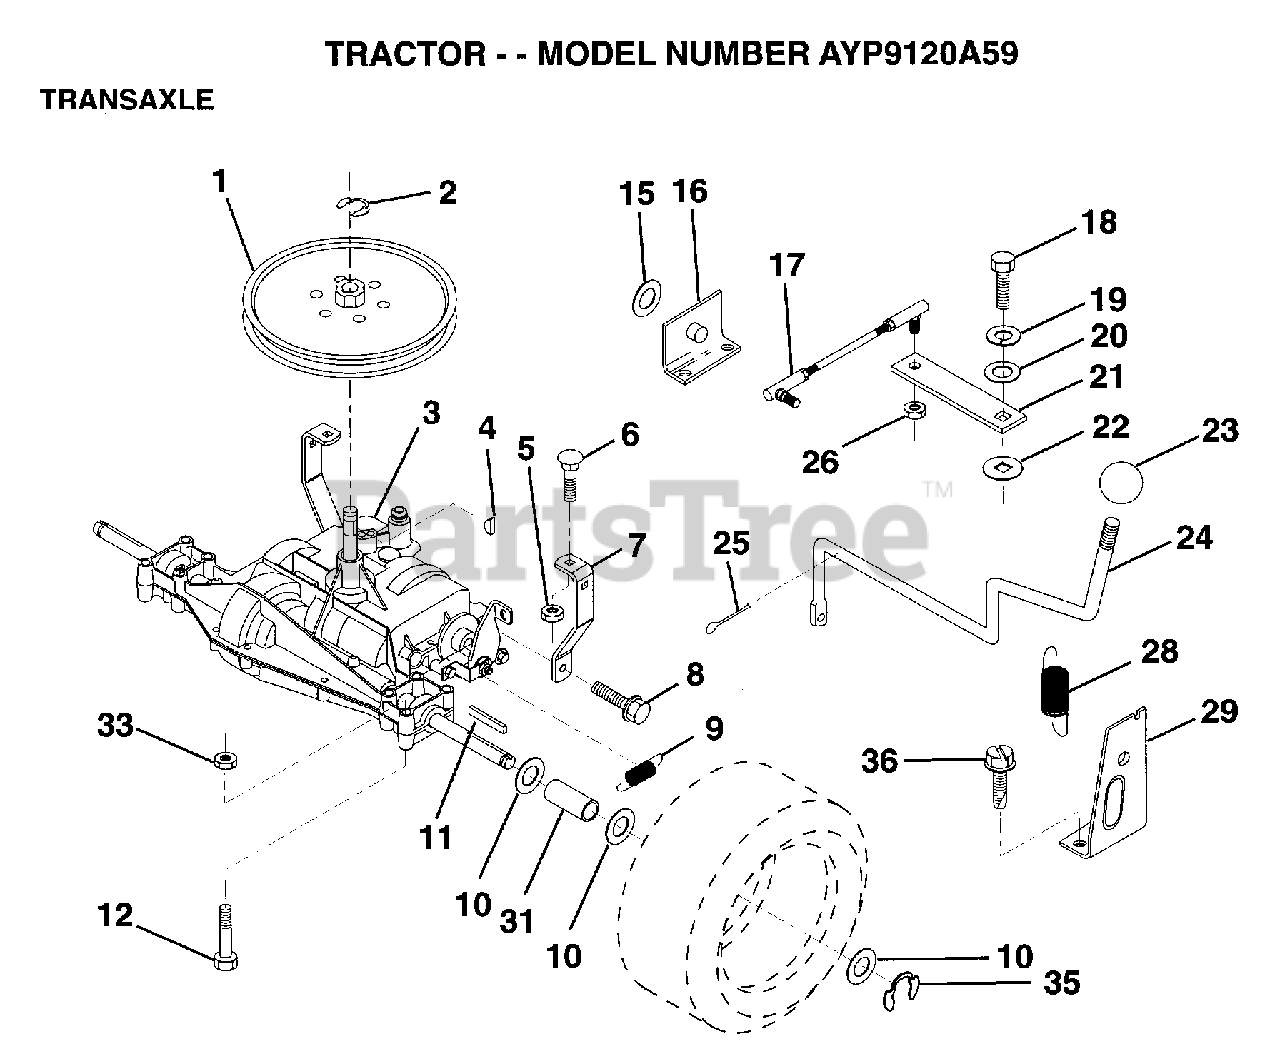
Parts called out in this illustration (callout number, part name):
1	PULLEY
6	BOLT
7	"STRAP,TORQUE"
8	SCREW
10	WASHER
11	SQUARE KEY
12	BOLT
16	"SUPT,HDLE SHT LH"
17	"LINK,SHIFT"
18	BOLT.1/4-28.W/PAT
19	LOCKWASHER
20	WASHER LT
21	ARM SHIFT
22	WASH-SHFT PLT LT
23	KNOB T (1/2-HOLE)
24	"ROD,SHIFT"
25	PIN COTTER 1/8
26	NUT.LOCK.5/16-24
28	"SPRING,EXT"
29	"SUPT,HDLE RH"
31	SPACER LT
34	LOCKWASHER.5/16.E
35	E-RING LT
36	SCREW
